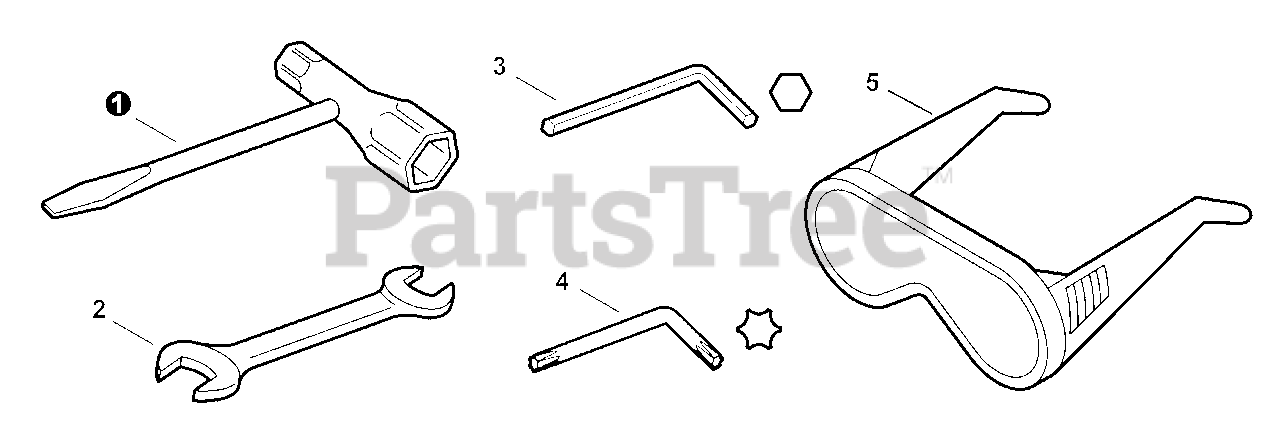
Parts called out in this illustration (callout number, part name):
1	T-WRENCH 10×19mm
2	SPANNER 8×10
3	WRENCH, ALLEN 4MM
4	WRENCH, ALLEN T27 80×30
5	GLASSES, SAFETY
